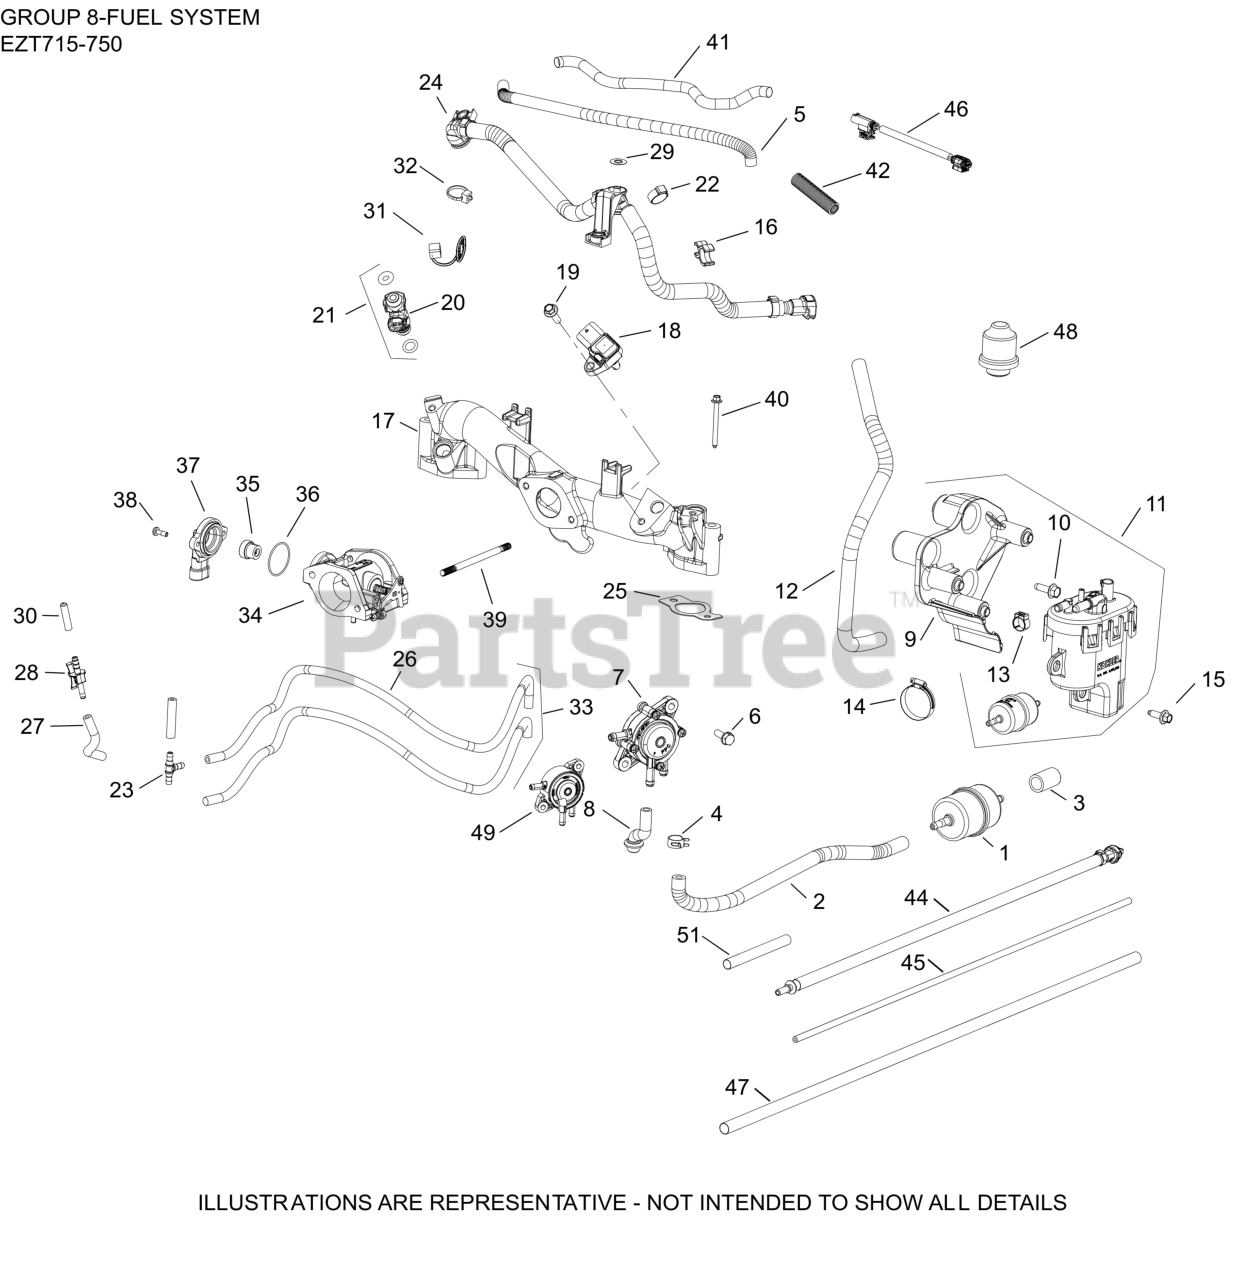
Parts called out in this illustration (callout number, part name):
1	FILTER, FUEL
4	SPRING CLAMP, HOSE
5	SLEEVE, ANTI-ABRASION
9	BAFFLE, FUEL MODULE
10	SCREW, THREAD FORMING
11	KIT, FUEL PUMP MODULE
12	SLEEVE, INSULATING
13	CLAMP, OETIKER
15	SCREW, HEX FLANGE (M6 W/DOG POINT)
16	RETAINER, CLIP
17	MANIFOLD MACHINED (EFI)
18	SENSOR, T-MAP
19	SCREW, FLG M6x1.0x20
20	INJECTOR, FUEL
21	KIT, FUEL INJECTOR O-RING
22	CLAMP, HOSE
23	TEE CONNECTOR
24	FUEL HOSE ASSY(ECV,FCV,EZT,EKT,PCH,PCV)
25	KIT, INTAKE MANIFOLD GASKET
26	HOSE, EVAPORATIVE 20"- (#24326143S)
27	HOSE EVAPORATIVE (WALBRO)
28	CONNECTOR, EVAPORATIVE
29	CLIP, RETAINER
30	CAP, MASKING
31	CAP, CONNECTOR
32	TIE, CABLE
33	HOSE, ASSEMBLY
34	BODY ASSEMBLY, THROTTLE W/TPS
35	MAGNET, TPS SENSOR
36	O-RING, TPS SENSOR
37	SENSOR, THROTTLE POSITION
39	STUD-USE 25 072 48-S
40	SCREW, HEX FLANGE (M6 W/DOG POINT)
49	PUMP, FUEL (PULSE)
NI	SCREW, HEX HEAD
NI	SLEEVE, ANTI ABRASION
